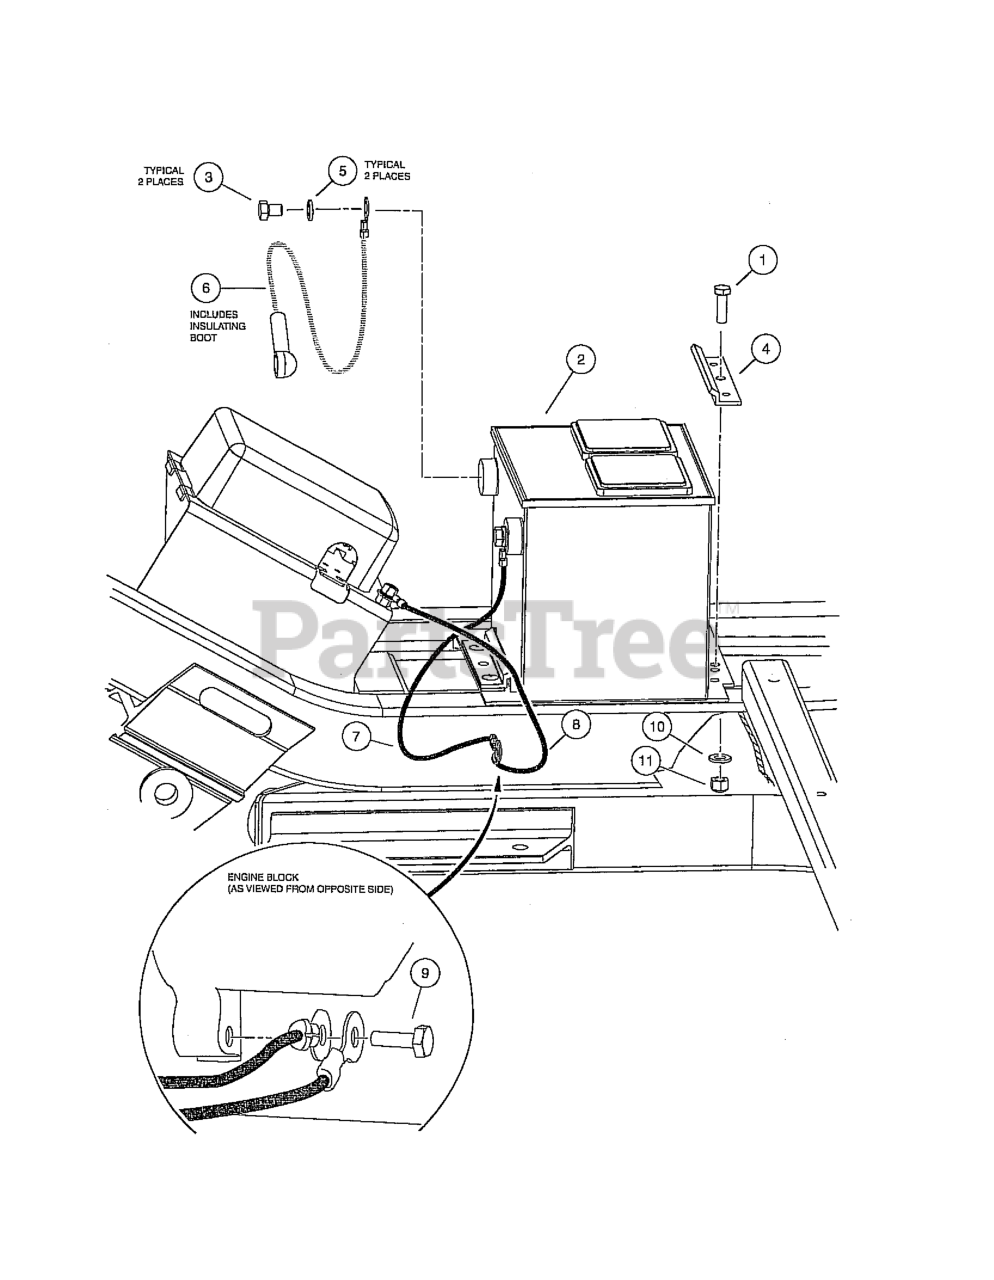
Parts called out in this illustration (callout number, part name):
1	SCREW HEX CAP
2	BATTERY, 12 VOLT
4	CLAMP - BATTERY
5	LOCKWASHER, 3/8 STAINLESS STL
6	WIRE ASM, #6 RED, AWD
7	WIRE ASM, #6 BLK, AWD, 300
8	WIRE ASM, #6 BLK, AWD, 250
9	BOLT, M6 X 1 X 16 LOCTITE
10	WASHER, 5/16 TYPE A FLAT
11	LOCKNUT, 5/16-18 NYLON INSERT
